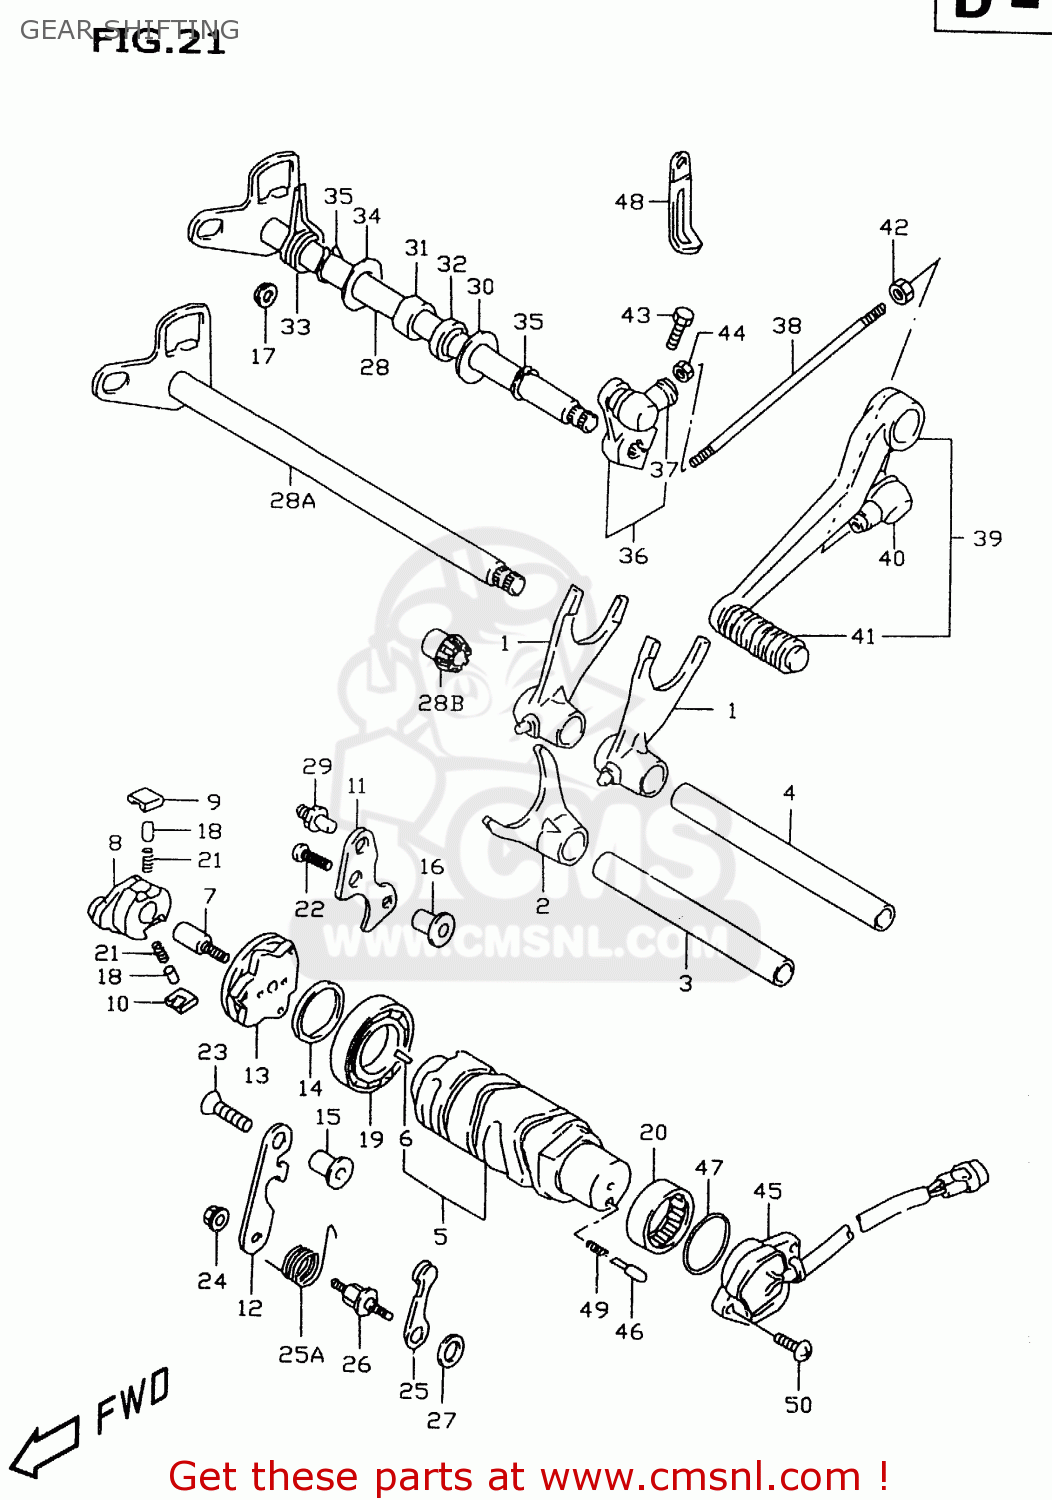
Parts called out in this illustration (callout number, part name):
1	FORK,GEAR SHIFT NO.1
2	FORK,GEAR SHIFT NO.3
3	SHAFT,GEAR SHIFT FORK
4	SHAFT,GEAR SHIFT FORK(L:128)
5	CAM,GEAR SHIFT
6	PIN
7	PIN,SHIFT CAM DRIVEN GEAR
8	SHIFTER,GEAR SHIFT CAM
9	PAWL,GEAR SHIFT NO.1
10	PAWL,GEAR SHIFT NO.2
11	LIFTER,GEAR SHIFT PAWL
12	GUIDE,GEAR SHIFT CAM
13	PLATE,GEAR SHIFT CAM
14	WASHER(25X32X3)
15	SPACER(6.1X10X16)
16	SPACER(6.1X10X16)
17	SPACER(7X10X5)
18	PIN(5X8)
19	BEARING(25X47X8)
20	BEARING(25X32X12)
21	SPRING
22	SCREW 6X30
23	SCREW
24	NUT
25	STOPPER,GEAR SHIFT CAM
25A	SPRING,SHIFT CAM STOPPER
26	SUPPORT,CAM STOPPER ARM
27	WASHER
28	SHAFT,GEAR SHIFT
28A	SHAFT,GEAR SHIFT
28B	BUSH,GEAR SHIFT SHAFT
29	STOPPER,GEAR SHIFT CAM
30	WASHER(14X29X0.8)
31	BEARING(14X20X12)
32	SEAL,OIL(14X22X6)
33	SPRING
34	WASHER
35	CIRCLIP
36	ARM,GEAR SHIFT LINK
37	COVER,DUST
38	ROD,GEAR SHIFT LINK(L:165)
39	LEVER ASSY,GEAR SHIFT
40	COVER,DUST
41	RUBBER,GEAR SHIFT PEDAL
42	NUT
43	BOLT
44	NUT
45	BASE ASSEMBLY,GEAR SHIFT TERMINAL
46	PIN(5X15.5)
47	O RING(D:2.4,ID:25.7)
48	CLAMP(L:45)
49	SPRING
50	SCREW
